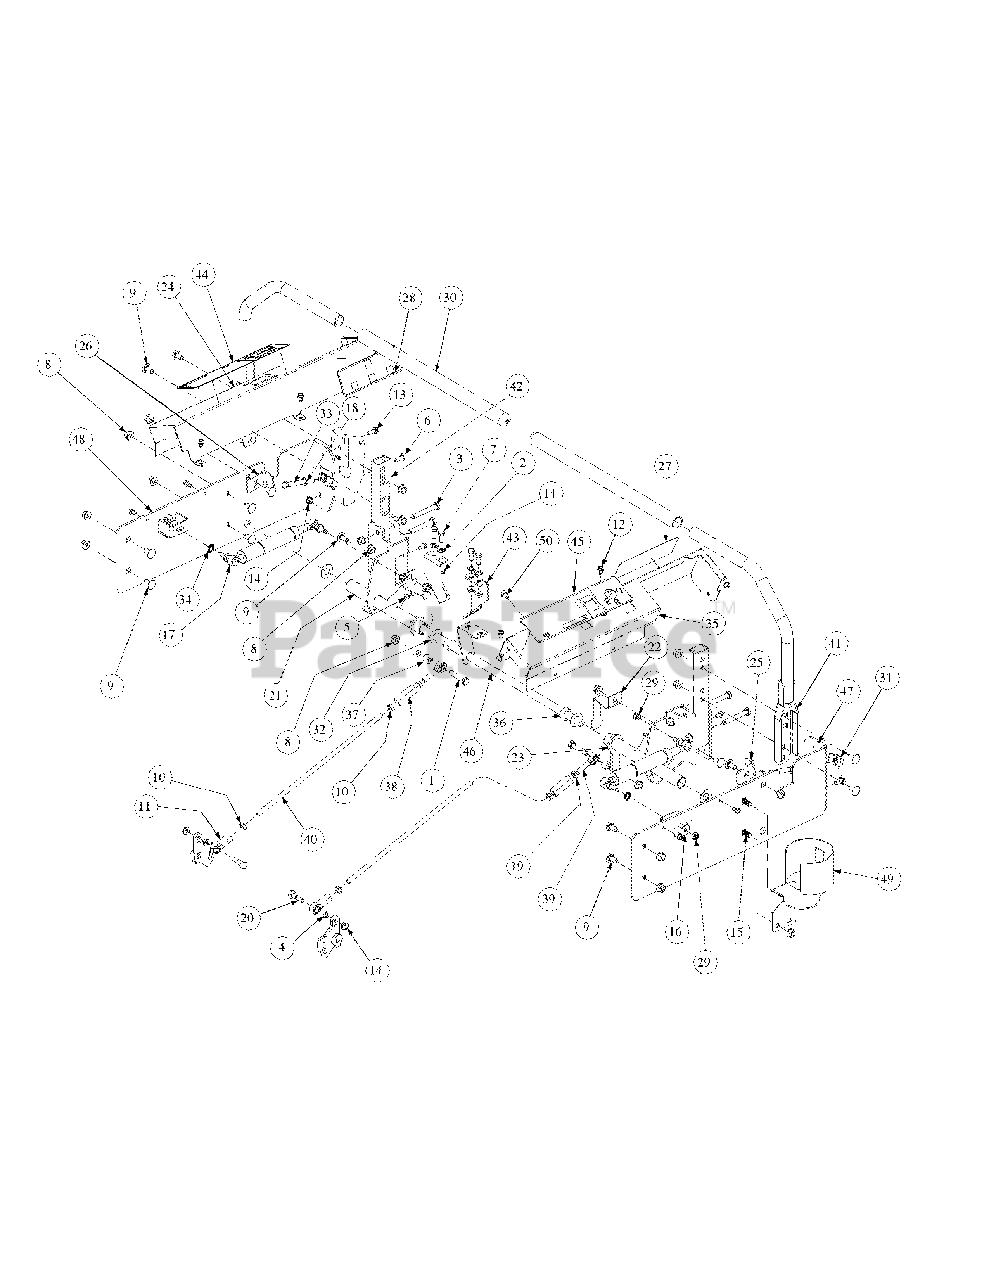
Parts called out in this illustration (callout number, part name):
1	Capscrew, 3/8-16 x 1-3/4
2	Flat Washer, 5/16
3	HHCS, 3/8-16, 2.25
4	5/16, Lock Washer
5	Grease Fitting, 90 degree
6	HHCS, 5/16-18 x 1.0
7	Hex, Cap Screw, 5/16-18 x 3/4
8	Hex Nut, 3/8-16, Lock Flange
9	Carriage Bolt, 3/8-16 x .75
10	Hex Jam Nut, 3/8-24
11	B/Joint, 3/8-24, Right Hand Female
12	Screw, TT, 1/4-20, 0.5, Hex Index Washer
13	Screw, TT, 1/4-20, 0.75, Hex Index Washer
14	Nut, Lock, Hex Flange, 5/16-18
15	Carriage Bolt, 3/8-16 x 1
16	Belle Washer, .325 x .930 x .045
17	Cylinder Return to Neutral
18	Nut, 3/8-16, Jam
19	Nut, 3/8-24, Jam, LH Third
20	Screw, Shoulder Control Rod
21	Hub Assy, Control LH Bearing
22	Lever, Safety Switch
23	Hub Assy, Control RH Bearing
24	Control Panel, LH
27	Decal Right Hand Control
28	Decal, Left Hand Control
29	Nut, Hex, Center Lock, M8
30	Grip, 1.0
31	U-Nut, 3/8-16, .75
32	Flat Washer, 5/8 Nylon
33	HHCS, 3/8-16, 3.00
34	External Washer, 3/8
35	Control Panel, RH
36	Shaft Collar
37	Spacer, .385ID x .625 OD x .50 Lg
38	Turnbuckle
39	B/Joint, 3/8-24, Left Hand Female
40	Rod Connector 3/8 OD x 14.25
41	Lapbar, Handle Assembly
42	Mounting Handle
43	Switch Mounting Bracket, Lapbar
44	Decal, Left Hand Console
45	Decal , Right Hand Console
46	Shaft Control Brake Steering
47	Side Panel, Control, Right
48	Side Panel, Control, Left
49	Cup Holder Assembly
50	Screw Button Head, 1/4-20 x .5
